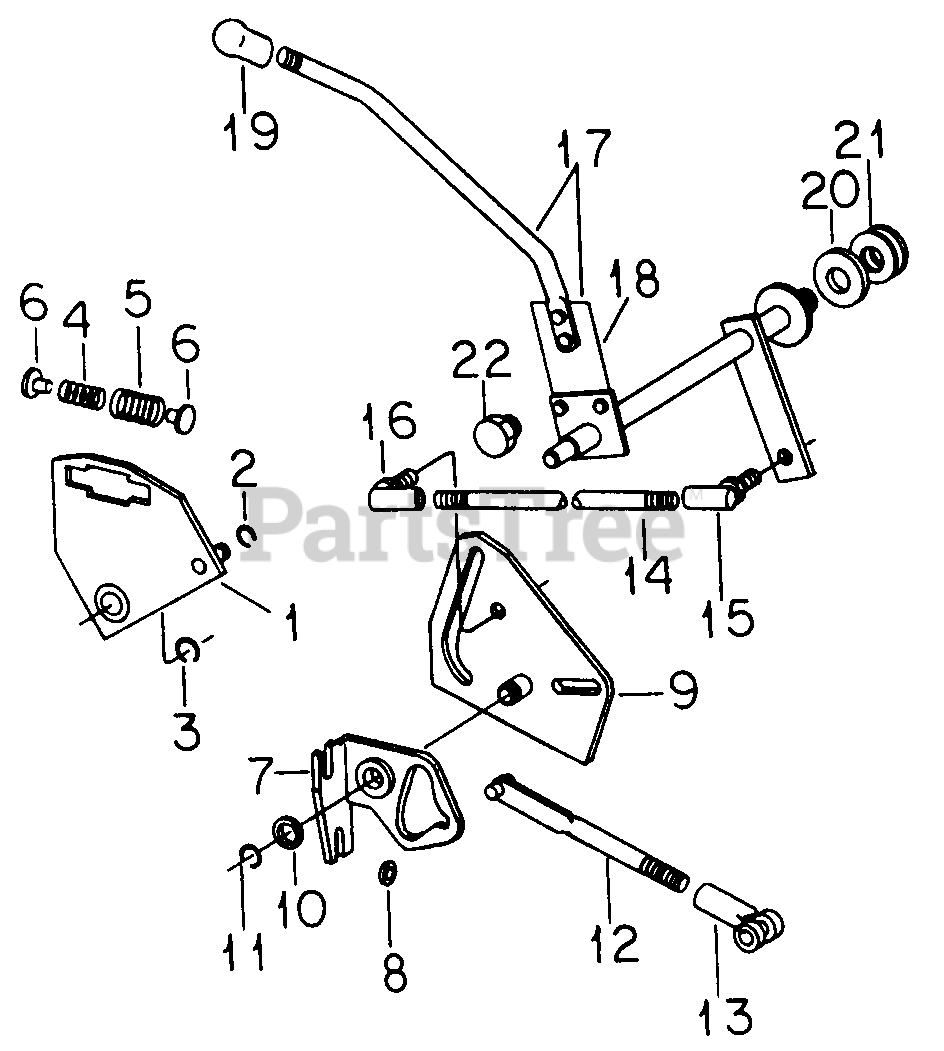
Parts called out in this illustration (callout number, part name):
1	Plate Assy, Damper Spring
2	Ring, Retaining
3	Ring, Retaining
4	Spring, Damper LT
5	Spring, Damper HV
6	Pin, Damper Spring Guide
7	Bracket Assy, Cam Pivot
8	Washer, .406 X .812 X .065
9	Cam Assy, Control
10	Washer, Cam Retaining
11	Ring, Cam Retaining
12	Rod Assy, Control
13	Clevis, 3/8 Rod End
14	Stud, Connecting
15	Joint, 5/16-24 Znd Ball
16	Joint, 5/16-24 Znd Ball
17	Shaft Assy, Cross
18	Spring, Flat
19	Knob, Control
20	Disc, Friction
21	Washer, Belleville
22	Bearing, Rockshaft
